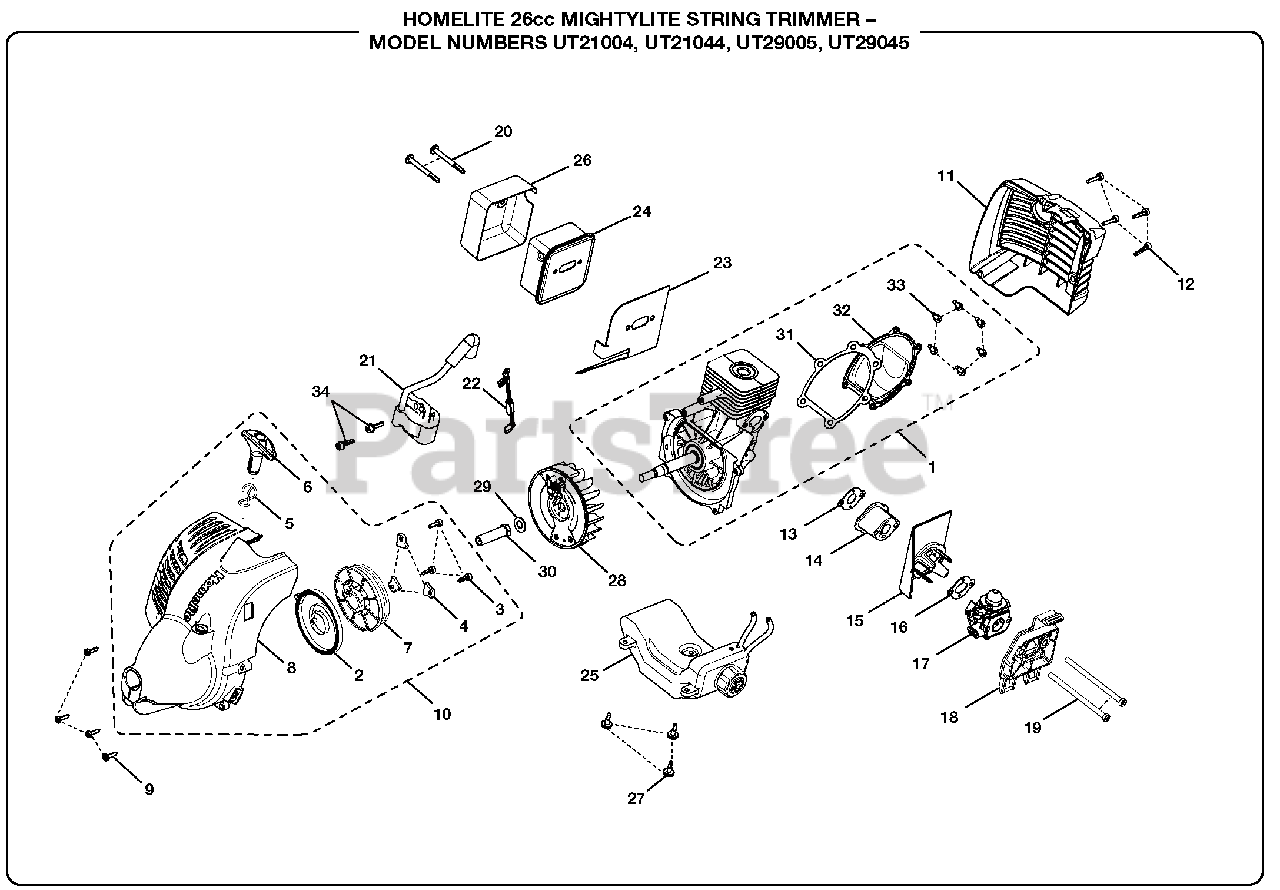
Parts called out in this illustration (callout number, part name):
1	Short Block Assembly (Inc. Key Nos. 31-33)
2	Spring & Container Assembly
3	Screw (M4 x 14 mm)
4	Pulley Retainer
5	Starter Rope
6	Starter Grip
7	Easy Starter Assembly
8	Front Housing Assembly
9	Screw (M4 x 16 mm)
10	Starter Housing Assembly (Inc. Key Nos. 2-8)
11	Rear Housing
12	Screw (M4 x 18 mm)
13	Intake Gasket
15	Heat Dam Deflector
16	Carburetor Gasket
17	Carburetor
18	Air Box Base
19	Screw (M5 x 70 mm)
20	Screw (10-24 x 2-1/8 in.)
21	Ignition Module
22	Lead Assembly
23	Muffler Gasket
24	Muffler Assembly
25	Fuel Tank Assembly w/Cap
26	Heat Shield
27	Screw (M4 x 10 mm Shoulder)
28	Flywheel Assembly
29	Washer
30	Drive Connector
31	Gasket
32	Crankcase Cover
33	Screw (M4 x 12 mm)
34	Screw (M4 x 19 mm)
